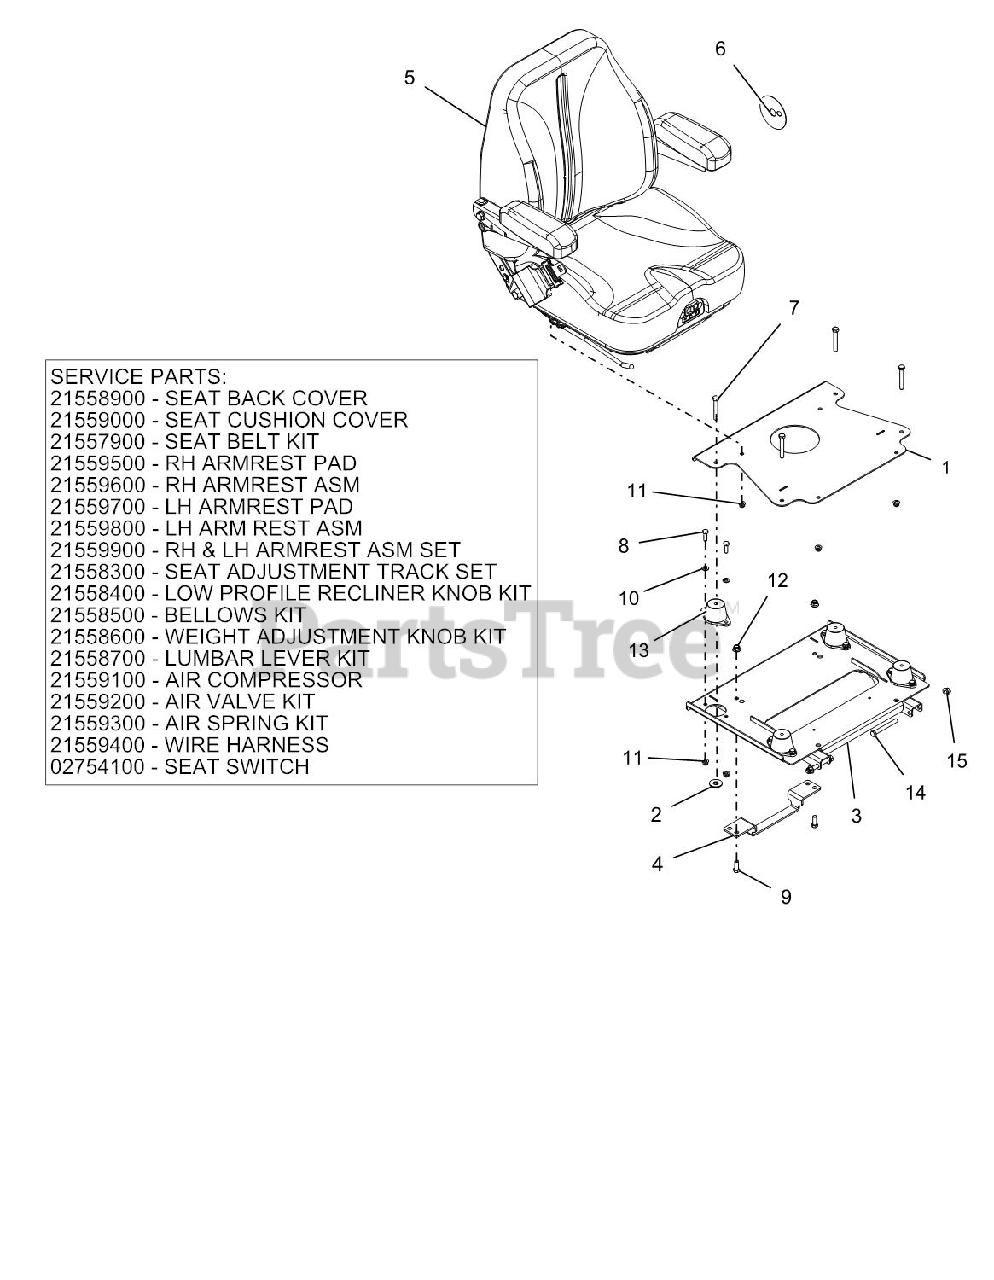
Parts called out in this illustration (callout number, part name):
1	WLDMT, SEAT MOUNTING
2	WLDMT, SEAT RETAINER
3	SEAT ISO MTG WMT W/SAFETY DECALS
4	BRKT, SEAT LATCH-BLACK
5	SEAT, AIR SUSPENSION
5	SEAT BACK COVER
5	SEAT CUSHION COVER
5	SEAT BELT KIT
5	RH ARMREST PAD
5	RH ARMREST ASM
5	LH ARMREST PAD
5	LH ARMREST ASM
5	RH & LH ARMREST ASM SET
5	SEAT ADJUSTMENT TRACK SET
5	LOW PROFILE RECLINER KNOB KIT
5	BELLOWS KIT
5	WEIGHT ADJUSTMENT KNOB KIT
5	LUMBAR LEVER KIT
5	AIR COMPRESSOR
5	AIR VALVE KIT
5	AIR SPRING KIT
5	WIRE HARNESS
5	SEAT SWITCH
6	PLATE, DIESEL SEAT RECLINE LIMIT
7	BLT-HEX .38-16X2.50 FTH GR5 YWZC
8	BLT-HEX .31-18X1.00 GR5 YWZC
9	BLT-HEX .38-16X1.00 GR5 YWZC
10	WSHR-FL-STL.344X.688X.065YWZC
11	NUT-LK-NYL-FLG .31-18 YWZC
12	NUT-LK-NYL-FLG .38-16 YWZC
13	MOUNT, ISOLATOR
14	BLT-HEX .38-16X3.25 GR5 YWZC
15	NUT-LK-NYL-FLG .38-16 YWZC
